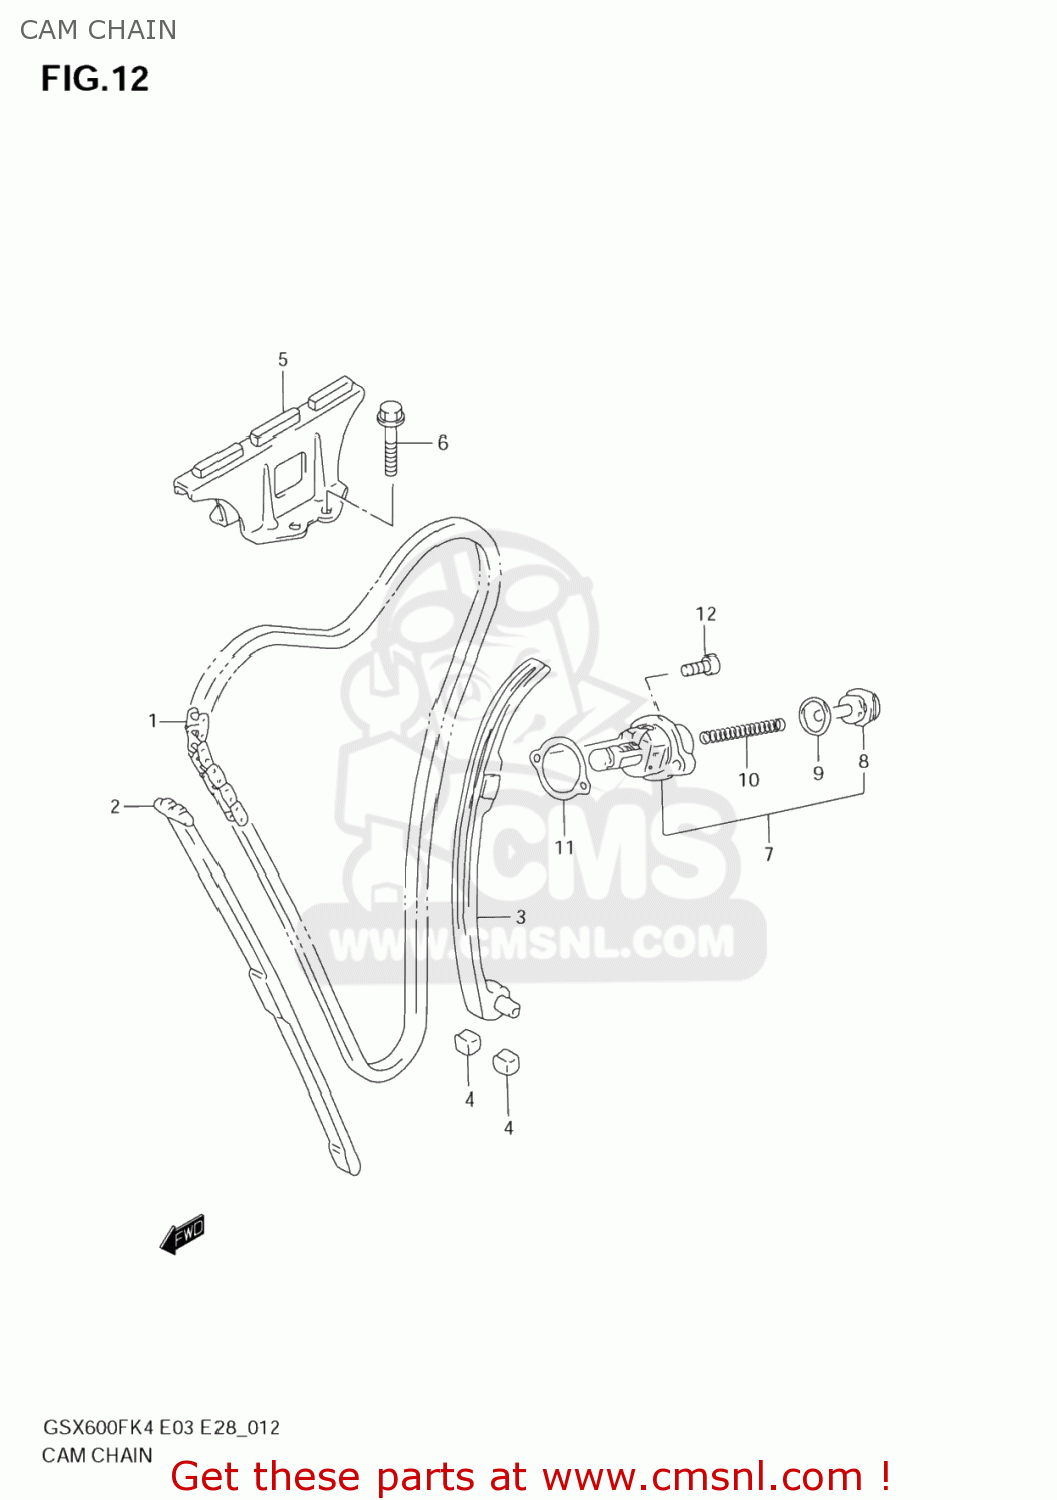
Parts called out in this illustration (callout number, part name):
1	CHAIN,CAMSHAFT DRIVE
2	GUIDE,CAM CHAIN NO.1
3	TENSIONER,CAM CHAIN
4	CUSHION,CAM CHAIN TENSIONER
5	GUIDE,CAM CHAIN NO.2
6	BOLT
7	ADJUSTER ASSY,TENSIONER
8	PLUG
9	GASKET (NAS)
10	SPRING
11	GASKET,TENSIONER ADJUSTER (NAS)
12	BOLT,CL.COVER
